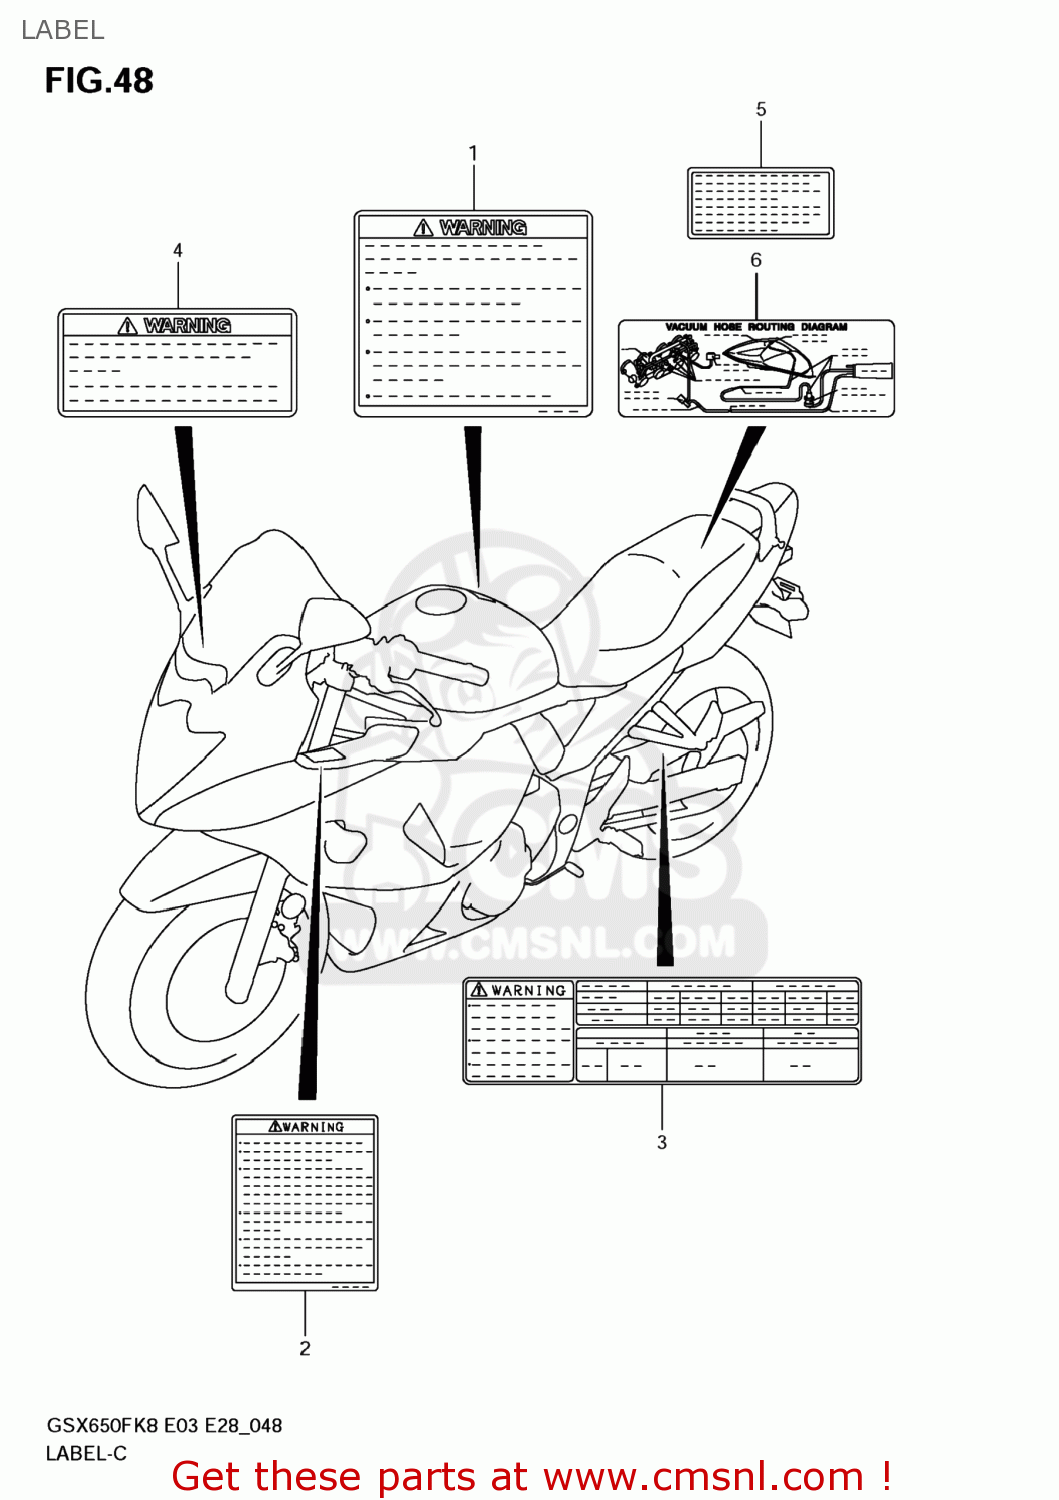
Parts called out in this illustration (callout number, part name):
1	LABEL,GENERAL WARNING
2	LABEL,SCREEN
3	LABEL,TIRE INFORMATION
4	LABEL,WARNING STEERING
5	LABEL,MANUAL NOTICE
6	LABEL,VACUUM HOSE ROUTING
7	MANUAL,OWNER'S
